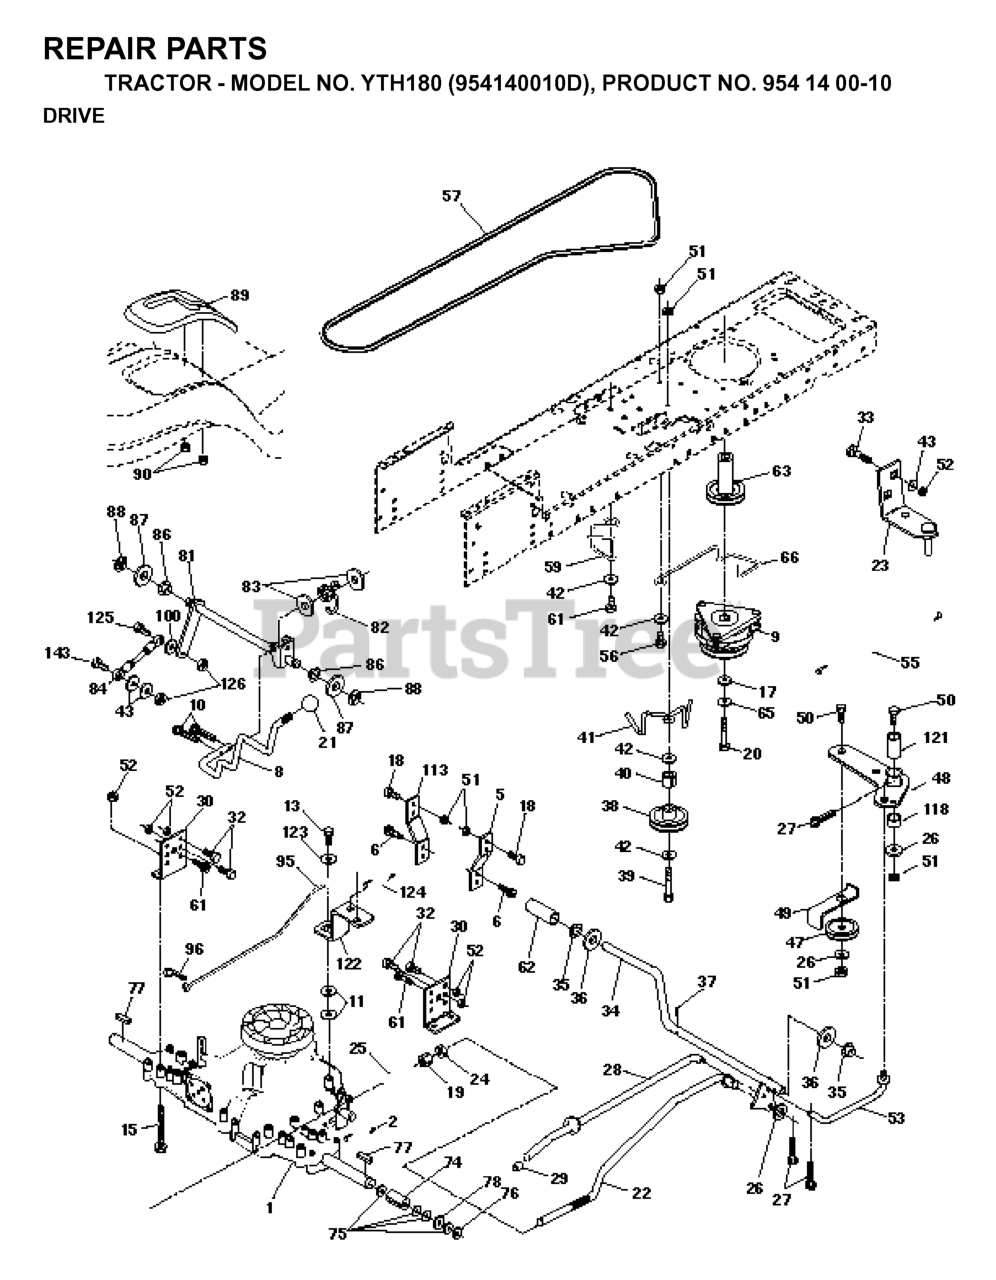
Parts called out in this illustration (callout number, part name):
2	SPRING,BRAKE RETURN
5	STRAP TORQUE
6	SCREW.THDROL.5/16-18X3/4.TTY
8	ROD SHIFT FENDER
9	CLUTCH.ELECT.CVX.105 FT/LB.
10	PIN COTTER
11	WASH-SHFT PLT LT
13	BOLT 1/4-28X3/4
15	BOLT HEX 5/16-18 GR 5
19	NUT
20	BOLT HEX
21	KNOB.DELUXE.(PISTOL.GRIP).BLAC
23	BRACKET ASM MTG
24	NUT
25	SPRING ROD LT
26	WASHER
27	COTTER PIN
28	ROD BRAKE PARK LT
29	PLUNGER CAP
30	BRACKET TRANSAXLE
32	BOLT
33	RP BOLT 5/16-18 X3/4 ZN/YEL GR
34	SHAFT, FOOT PEDAL
35	BEARING.NYLON
37	DRIVE PIN
38	PULLEY.IDLER.FLAT
41	KEEPER, BELT IDLER
42	WASHER
47	IDLER PULLEY
48	BELLCRANK ASSEMBLY
49	RETAIN BELT
50	BOLT
52	LOCKNUT
53	LINK, CLUTCH LT
55	SPRING, RETURN LT
57	RP.V-BELT
59	KEEPER CENTER SPAN
61	SCREW
62	COVER, PEDAL (1 2)
63	PULLEY CLU ELEC
65	LOCKWASHER
66	KEEPER BELT ENGINE
77	SQUARE KEY
82	SPRING,TORSION
83	WASHER
86	BUSHING.STEERING.ROD LTB-WSL
89	CONSOLE SHIFT
90	NUT.PUSH.3/16
95	ROD ASM BYPASS PVST
96	RETAINER M
100	WASHER M
113	STRAP TORQUE LH LT
118	SPACER BELLCRANK
121	NYLINER CLUTCHING
122	PLATE BYPASS PVST
124	RETURN SPRING
125	BOLT.FIN.HEX.5/16-18UNC X 1.00
143	BOLT.5/16-18X1-1/4 FULL.THREAD
